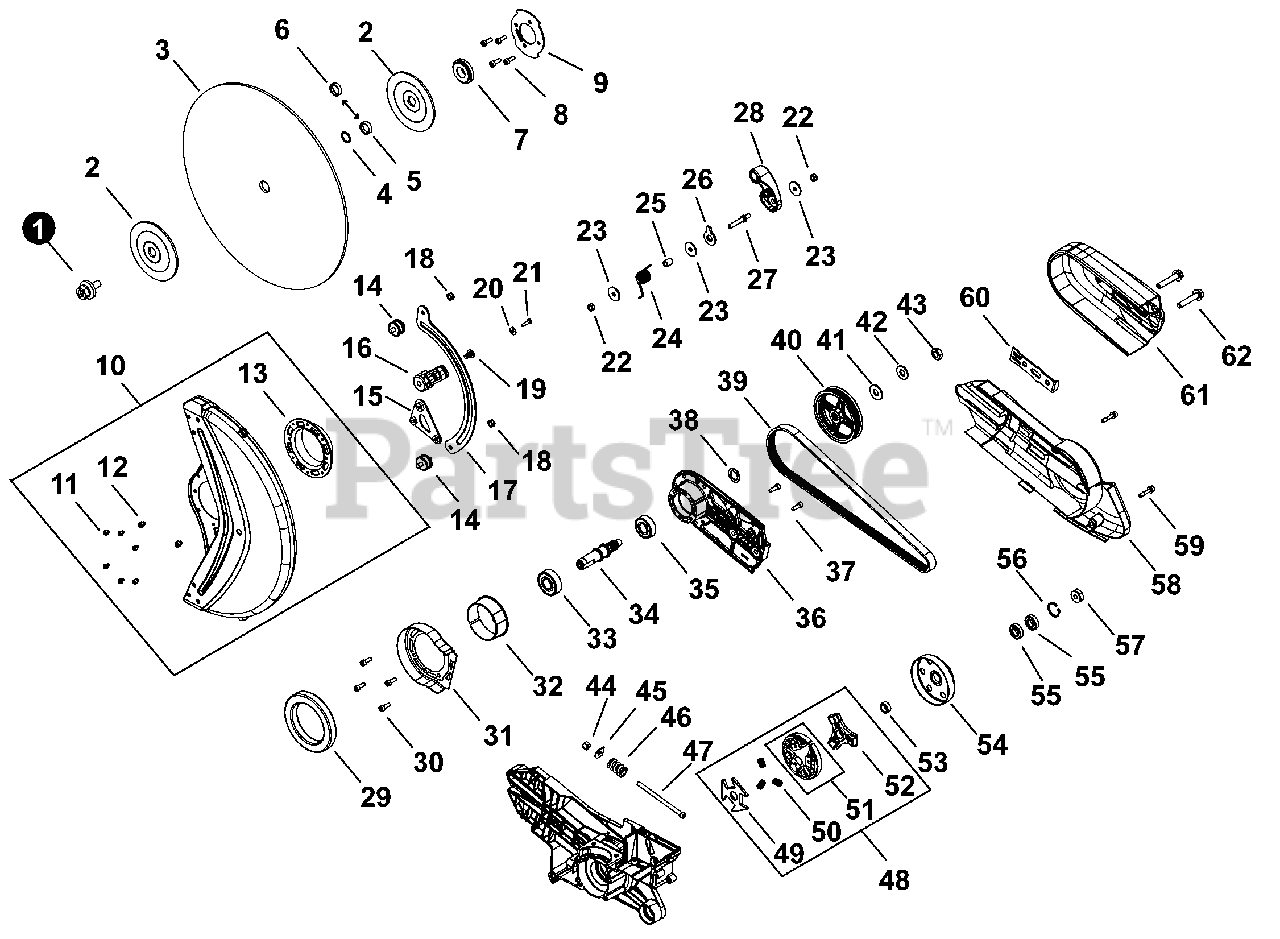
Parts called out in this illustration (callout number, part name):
1	BOLT ASSY
2	FLANGE, CUTTER
3	CUT-OFF WHEEL
4	RING, SNAP
5	COLLAR - 20
6	COLLAR - 25.4
7	COLLAR 18
10	COVER, CUTTER
14	CUSHION 6
17	PLATE, ADJUST
18	NUT, LOCK
21	SCREW 4×16
22	NUT, LOCK
23	WASHER Ø23ר6.5×2 MM
24	SPRING, TORSION
31	COVER, SPRING
32	RING, SLIDE
33	BEARING, BALL 6203
34	SHAFT, DRIVE
35	BEARING, BALL 6202 DDU
36	CASE ASSY
39	BELT, DRIVE
41	WASHER 11
42	WASHER, CONICAL
43	NUT 3N-10
46	SPRING, COIL
48	CLUTCH ASSY
49	BOSS, CLUTCH B
50	SPRING, CLUTCH
51	CLUTCH SHOE SET
52	BOSS, CLUTCH B
53	COLLAR 12
54	DRUM, CLUTCH
55	BEARING, BALL
56	RING, SNAP
58	COVER, CUTTER ARM
60	PLATE, EYE
61	COVER, CUTTER ARM
